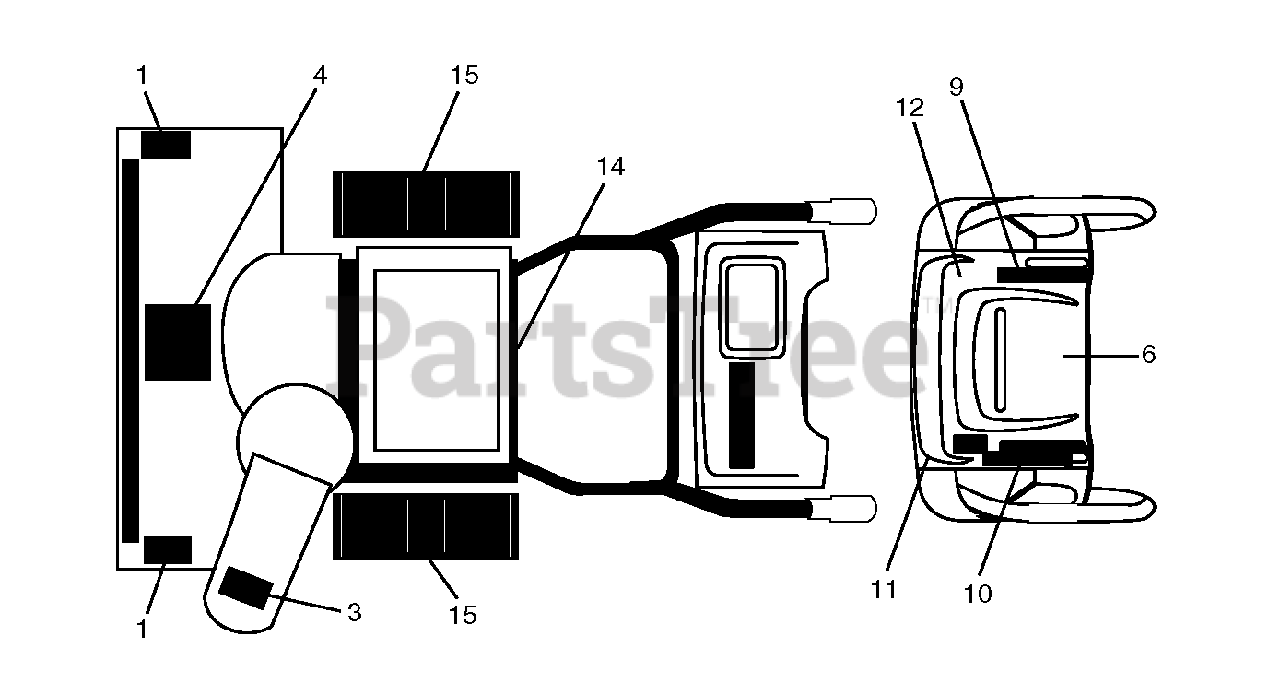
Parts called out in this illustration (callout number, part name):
1	DECAL.AUGER.SAFETY.
3	DECAL.CHUTE.SAFETY.
4	DECAL.AUGER."
9	DECAL.CONS.RH.INST.GRY
10	DECAL.CONS.LH.REM TANK.INST.GR
11	DECAL,HEIGHTADJUST
12	DECAL.CONSOLE.HAND.WARMER
14	DECAL.FENDER
15	DECAL.BELT.GUARD.
